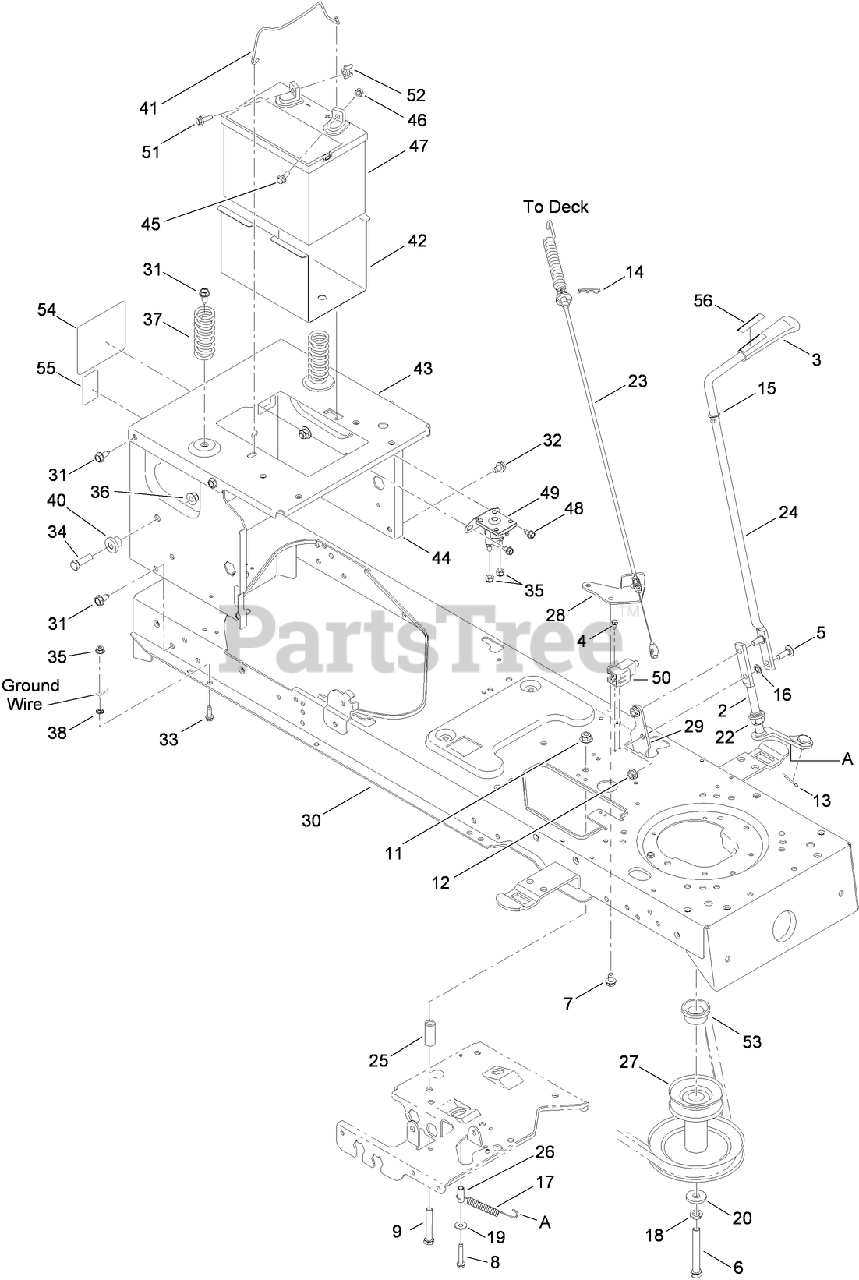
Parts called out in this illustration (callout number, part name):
2	LEVER-ENGAGE, PTO
3	KNOB-PTO
4	BOLT-SHOULDER
5	BOLT-CARR
6	SCREW-HH
7	SCREW-TAP
8	SCREW-HWH
9	SCREW-HH
11	NUT-LOCK, FLANGE
12	NUT-LOCK, FLANGE
13	PIN-COTTER
14	PIN-CLICK
15	WASHER-FLAT
16	NUT-PUSH
17	SPRING-EXTENSION
18	WASHER-LOCK
19	WASHER-FLAT
20	WASHER-FLAT
22	BEARING-FLANGE, HEX (SPLIT)
23	CABLE-ENGAGE, DECK
24	HANDLE-ENGAGE, DECK
25	SPACER
26	SPACER
27	PULLEY-ENGINE
28	BRACKET-MOUNT, CABLE
29	BRACKET-STOP
30	LOWER FRAME ASM
31	SCREW-TAP
32	SCREW-TAP
33	SCREW-TAP
34	SCREW-HH
35	NUT-LOCK, FLANGE
36	NUT-LOCK, FLANGE
37	SPRING-COMPRESSION
38	WASHER-LOCK, EXTERNAL
40	SPACER-SHOULDER
41	ROD-HOLDDOWN, BATTERY
42	TRAY-BATTERY
43	BRACKET-FRAME, SEAT
44	FRAME-UPPER
45	BOLT-CARRIAGE
46	NUT-SEMS
47	BATTERY-245, CCA,DRY (FLAT TOP)
48	SCREW-TAP
49	SOLENOID-12V, 2 POST 2 TAB
50	SWITCH-INTERLOCK, NO/NC
51	BOLT-SHOULDER
52	NUT-WING
53	SPACER
54	DECAL-TORO
55	DECAL-HYDRO RELEASE
56	DECAL-PTO
